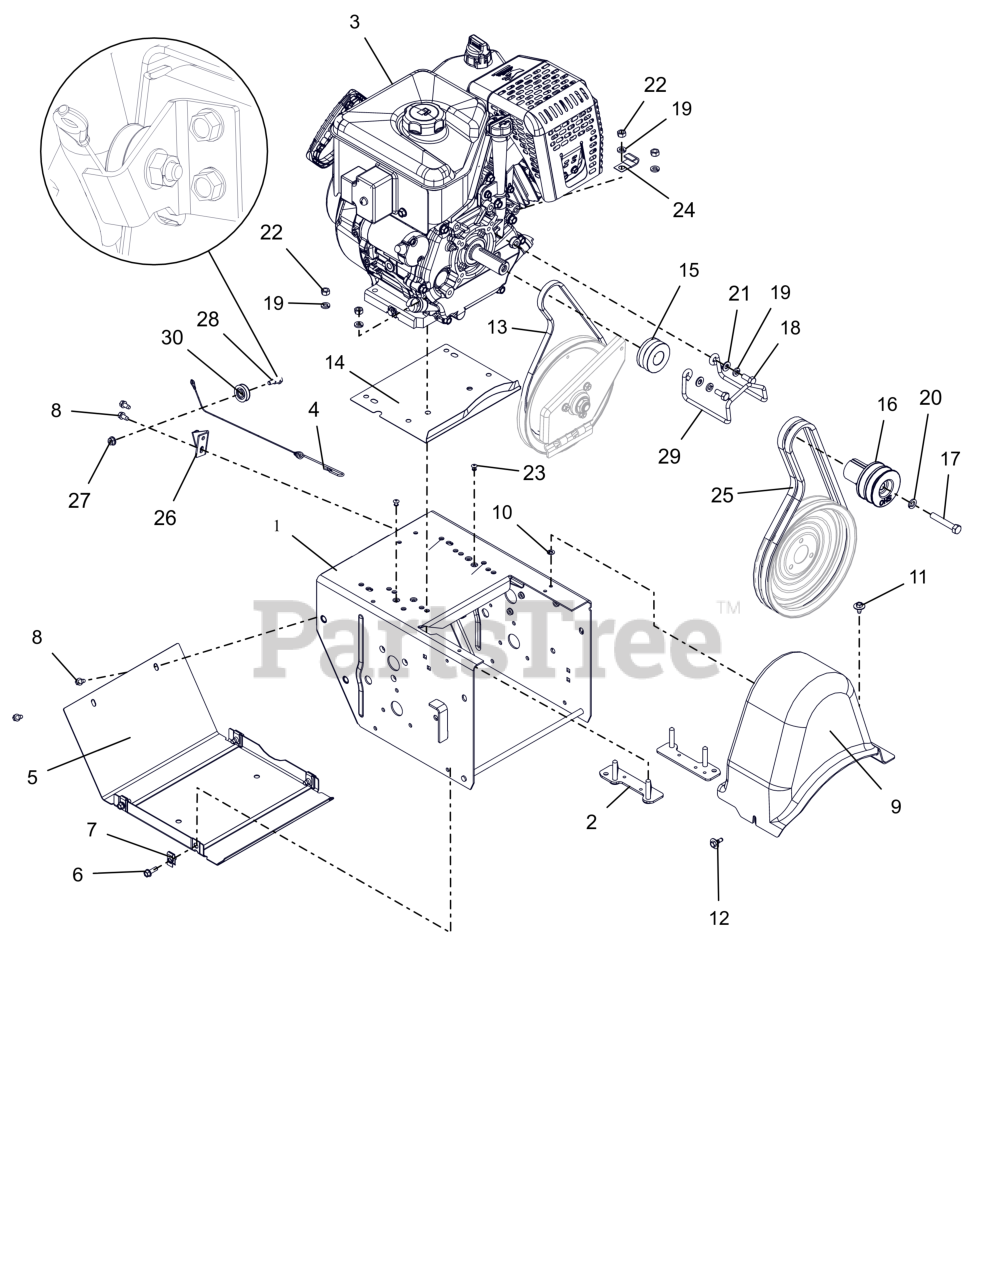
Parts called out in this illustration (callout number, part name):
1	FRAME, MAIN-DELUXE(WELDMENT)
2	STRAP, ENGINE-MEDIUM BLOCK
3	ENGINE, AX306 GEN3 240V60W
4	CABLE, LOWER TRACTION,SS & PRO
5	COVER, BOTTOM
6	BLT, HWH .25-20X.75 G5 ZCC
7	NUT-RTNR .25-20X.56
8	SCR-TAP .25-20X.50 HWH ZCC
9	COVER, BELT-LARGE
10	NUT-PUSH .25X.50 O.D.
11	SCR, TAP .25-20X.50 LG HWH ZCC
12	SCR-TAP .25-20X.5 CAPTIVE
13	V-BELT, 3L-WRAPPED
14	BAFFLE, WATER - LARGE BLOCK
15	SHEAVE, TRACTION (KEYLESS)
16	SHEAVE,ATTACHMENT-SHO 2 GRV
17	BLT, HEX .38-24X2.25 G5 ZCC
18	BLT, HEX .31-24X.750 G5 ZCC
19	WSHR, LK-HVY .312X.097 ZCC
20	WSHR,LK-REG .375X.094 ZCC
21	WSHR,FLT .344X.688X.065 ZCC
22	NUT, HEX .312-18 ZCC
23	RVT, POP .1875 ZCC
24	J-CLAMP
25	V-BELT, HA-RAW EDGE (SET)
26	BRACKET, CABLE PULLEY
27	NUT-LK-TOP-FLG .250-20 GF ZCC
28	BOLT, SHLDR -.375 X .375 X .25-20
29	FINGER, BELT
30	PULLEY, CABLE
